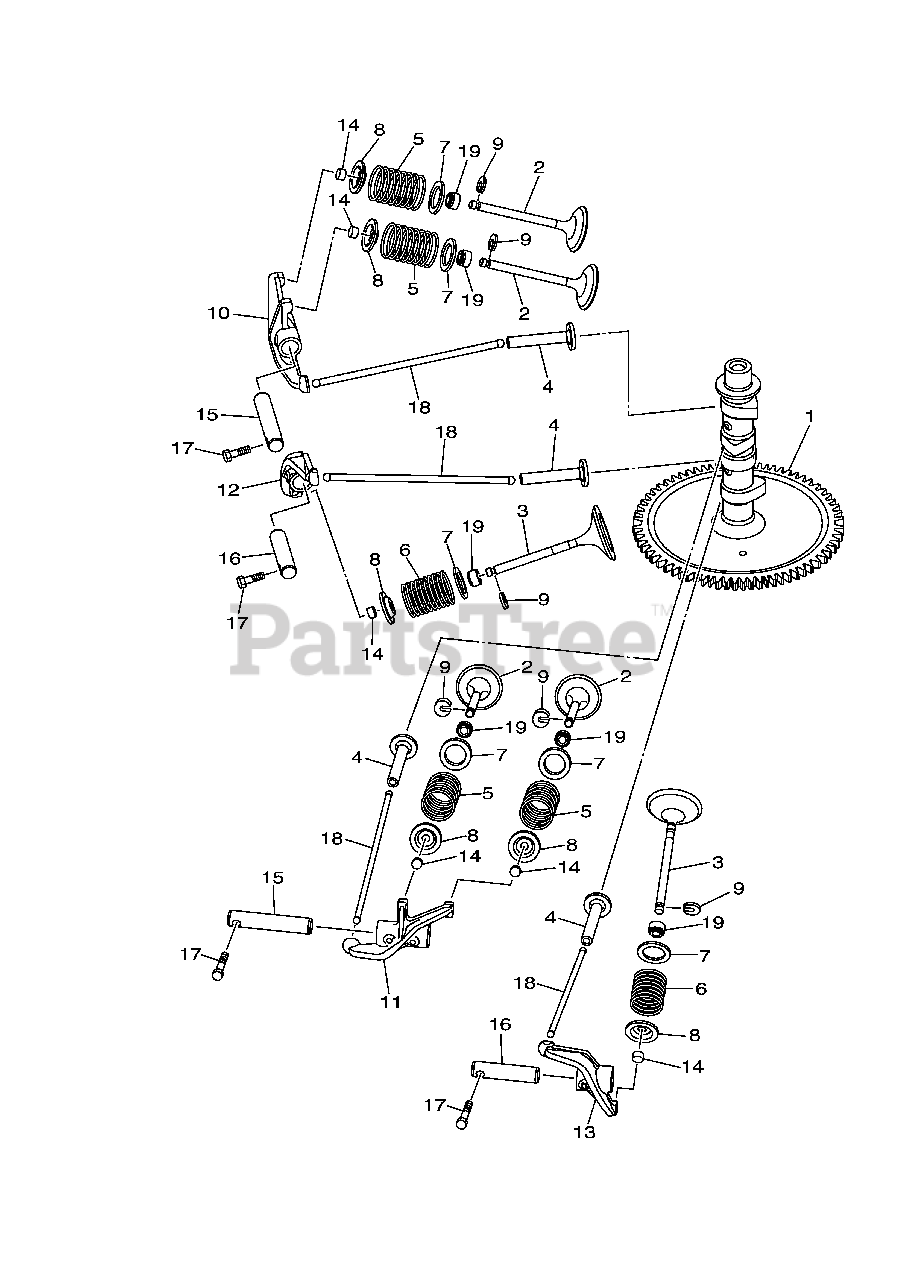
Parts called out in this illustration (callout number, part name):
1	CAMSHAFT 1
2	VALVE, INTAKE
3	VALVE, EXHAUST
4	LIFTER, VALVE
5	SPRING, COMPRESSION
6	SPRING, COMPRESSION
7	SEAT, VALVE SPRING
8	RETAINER, VALVE SPRING
9	LOCK, VALVE SPRING RETAINER
10	ARM, VALVE ROCKER
11	ARM, VALVE ROCKER 2
12	ARM, VALVE ROCKER 3
13	ARM, VALVE ROCKER 4
14	PAD, ADJUSTING 1.800
14	PAD, ADJUSTING 1.850
14	PAD, ADJUSTING 1.900
14	PAD, ADJUSTING 1.950
14	PAD, ADJUSTING 2.000
14	PAD, ADJUSTING 2.050
14	PAD, ADJUSTING 2.100
14	PAD, ADJUSTING 2.150
14	PAD, ADJUSTING 2.200
14	PAD, ADJUSTING 2.250
14	PAD, ADJUSTING 2.300
14	PAD, ADJUSTING 2.350
14	PAD, ADJUSTING 2.400
14	PAD, ADJUSTING 2.450
14	PAD, ADJUSTING 2.500
14	PAD, ADJUSTING 2.550
14	PAD, ADJUSTING 2.600
14	PAD, ADJUSTING 2.650
14	PAD, ADJUSTING 2.700
14	PAD, ADJUSTING 2.750
14	PAD, ADJUSTING 2.800
14	PAD, ADJUSTING 2.850
14	PAD, ADJUSTING 2.900
14	PAD, ADJUSTING 2.950
14	PAD, ADJUSTING 3.000
15	SHAFT, ROCKER
16	SHAFT, ROCKER 2
17	BOLT, HEXAGON
18	ROD, VALVE PUSH
19	SEAL, VALVE STEM
